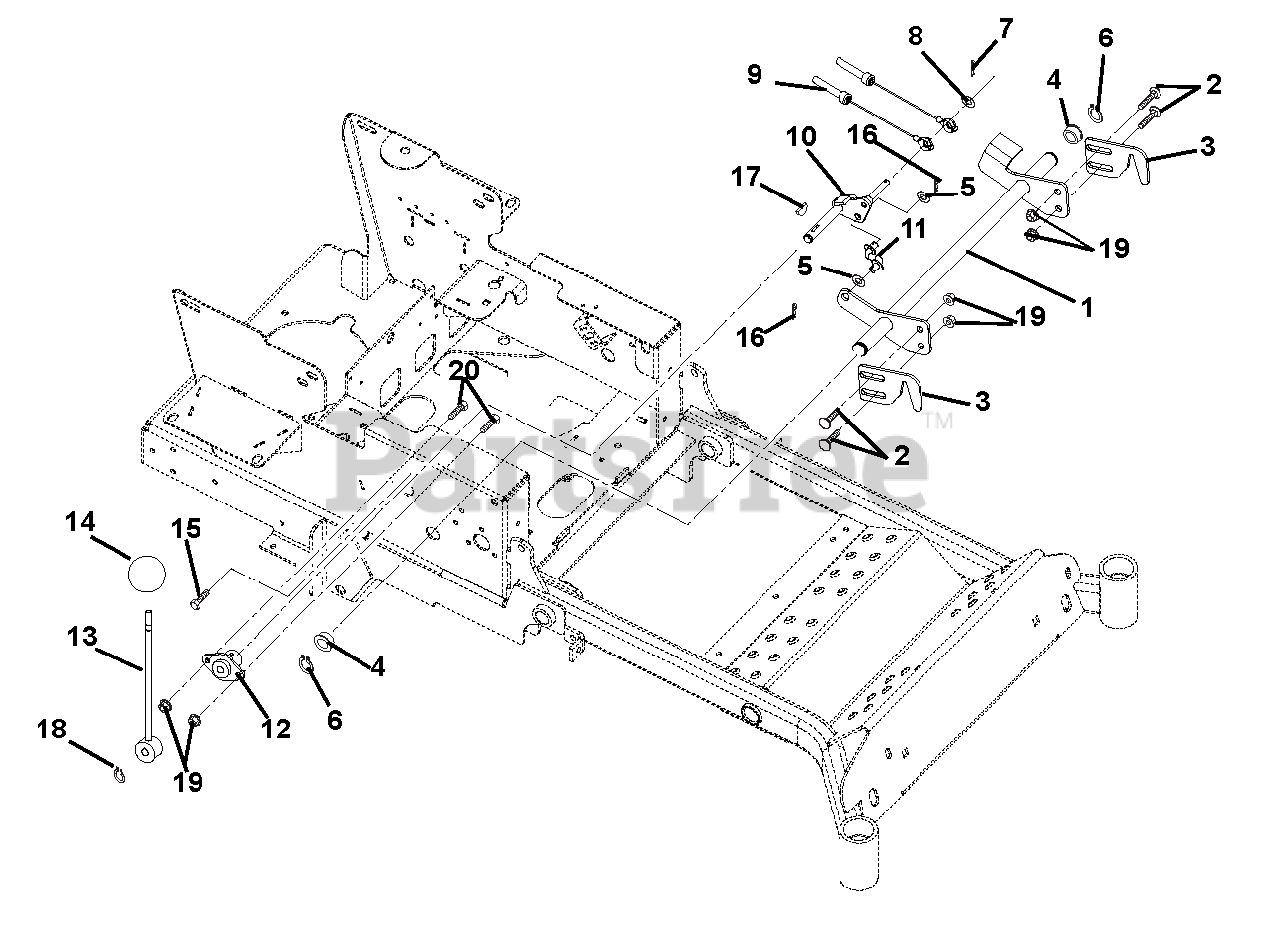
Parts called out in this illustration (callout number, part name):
1	WMT, NEUTRAL LOCK ARM
2	@BLT-RDHDSQNK .31-18X1.00 G5YZ
3	NEUTRAL LOCK LATCH - BLACK
4	BSHG-FLG .750X1.000X.625X1.250
5	@WSHR-FL-STL.406X.812X.065 YWZ
6	RG-RTNG-EXT .689X.078
7	PIN-HAIR INT .06X.18X.77
8	@WSHR-FL-STL.344X.688X.065YWZC
9	CABLE, BRAKE ACTUATING
10	WMT, PARK BRAKE ARM
11	LINK, BRAKE INTERLOCK
12	BUSHING, FLANGED
13	WMT, PARKING BRAKE LEVER
14	KNOB,BALL -BLACK 1.47" .375-16
15	@SCR-TAP .38-16X1.00 HWH TR YZ
16	PIN-HAIR, ENDRIES #25 YWZC
17	KEY-WDRF .13X.63 HRD#5
18	RG-RTNG-EXT .500X.050 (SNAP)
19	@NUT-LK-NYL-FLG .31-18 YWZC
20	@BLT-HEX .31-18X1.00 GR5 YWZC
